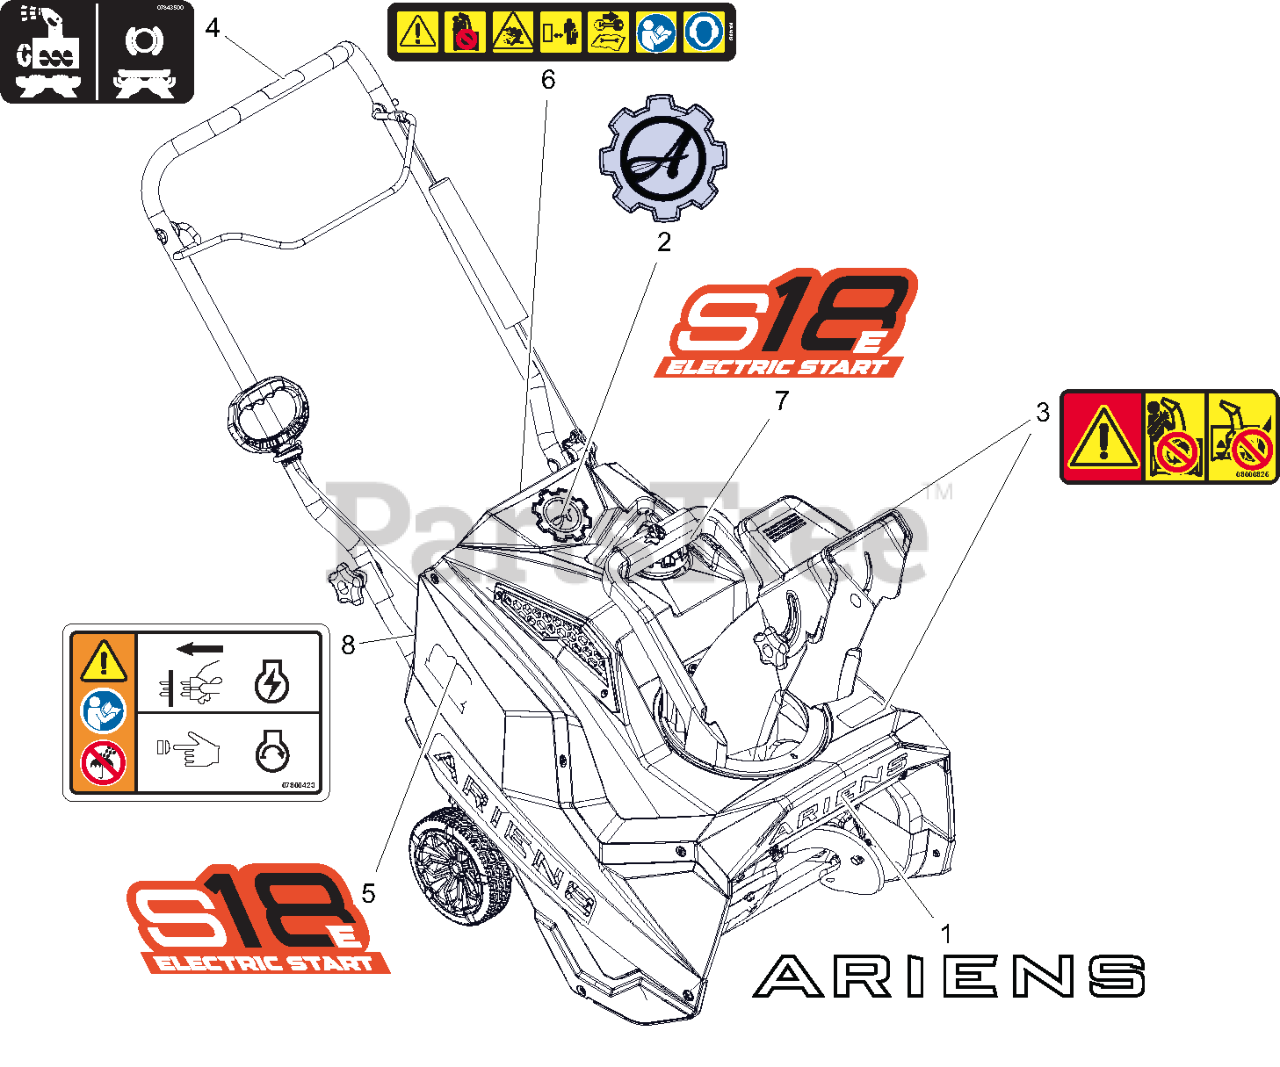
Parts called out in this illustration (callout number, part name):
1	DECAL, ARIENS - 9.625"
2	DECAL- ARIENS GEAR BADGE
3	DECAL, DANGER SINGLE STAGE
4	DECAL-AUGER/IMPELLER BAIL
5	DECAL, SHROUD COVER - RH E
6	DECAL, DASH - SAFETY
7	DECAL, SHROUD COVER - LH E
8	DECAL, ELECTRIC START
